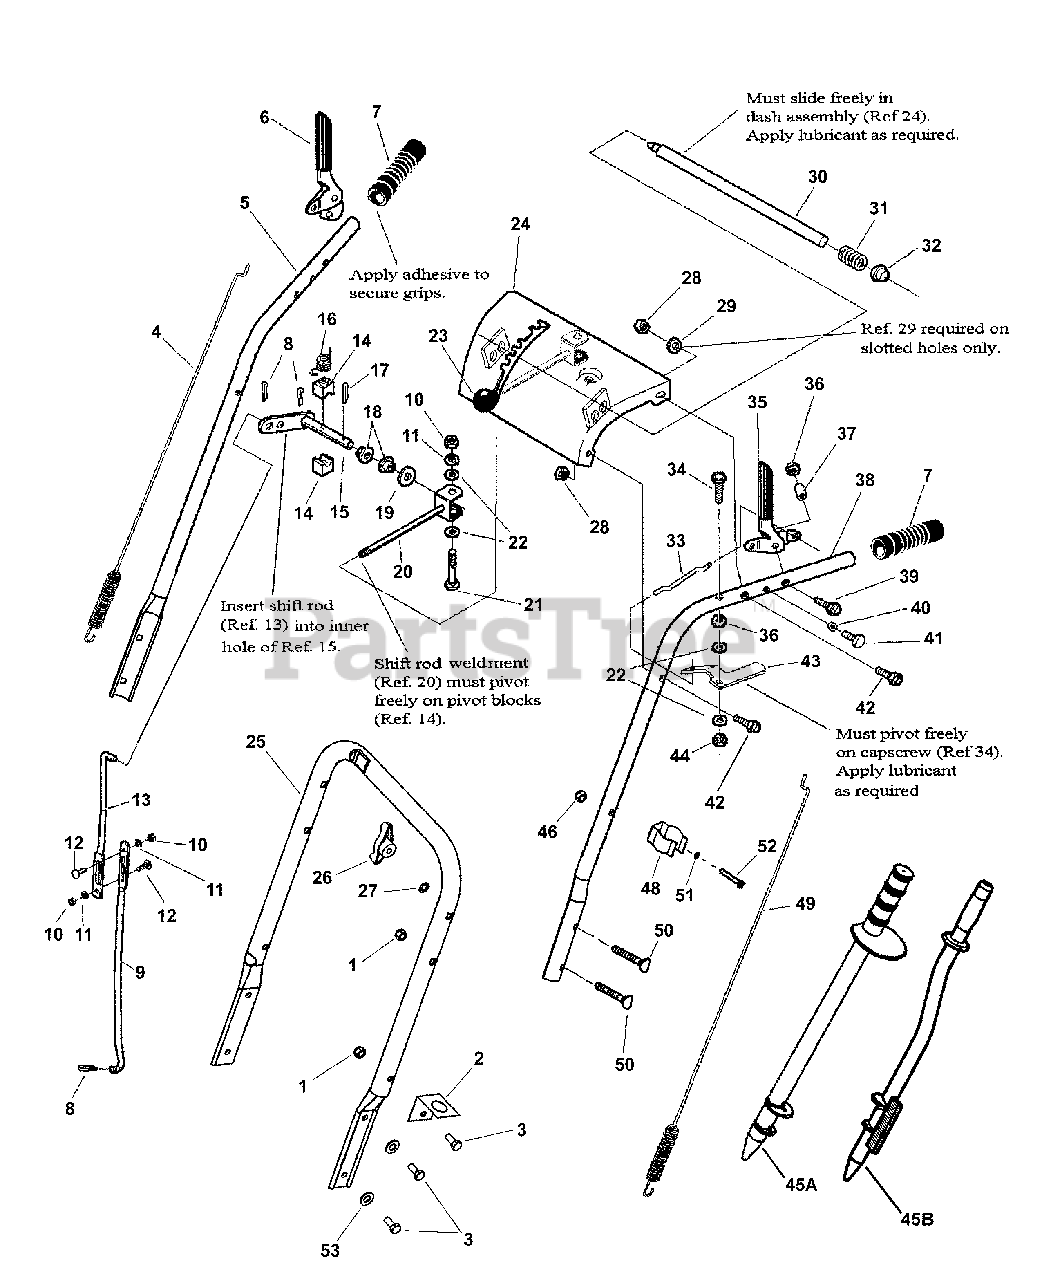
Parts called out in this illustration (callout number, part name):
1	NUT, 5/16-18 Hex Nyloc
2	BRACKET, Snow Stick- Lower
3	SCREW, 5/16-18 x 3/4" Hex Head Cap
4	CLUTCH CABLE, Auger Drive- RH
5	HANDLE, Upper, Right Hand
6	GRIP, Clutch, RH
7	GRIP, Foam, Black
8	HAIR PIN
9	ROD, Shift, Lower
10	NUT, 1/4-20 2B Hex
11	LOCKWASHER, 1/4" Spring
12	BOLT, 1/4-20 x 2" Short Square Neck Carriage, GR 5
13	ROD, Upper, Shift
14	BLOCK, Pivot
15	WELDMENT, Shift Rod Pivot
16	SPRING, Torsion
17	COTTER PIN, .125 x 1.00
18	BUSHING, .500 ID x .750 OD x .25
19	WASHER, 1/2" Flat (.531 ID x 1.250 OD x .08 Thick)
20	WELDMENT, Shift Rod
21	SCREW, 1/4-20 x 2-1/4" Hex Flange Lock
22	WASHER, .250 (.27 ID x .62 OD)
23	KNOB, Tapered - 3/8-16 Internal Thread- Red
24	WELDMENT, Dash
25	HANDLE, Lower
26	WING KNOB, 5/16-18
27	WASHER, 5/16" Internal Tooth Lock
28	NUT, 5/16-18 Hex Flange Nyloc
29	WASHER, .312 (.34 ID x .75 OD)
30	ASSEMBLY, Rod w/Pin
31	SPRING, Compression
32	PUSH NUT
33	ROD, Hold Down
34	SCREW, 1/4-20 x 2" Hex Head Cap, GR 5
35	GRIP, Clutch, LH
36	NUT, 1/4-20 Hex Centerlock
37	SPACER, Handle
38	HANDLE, Upper, Left Hand
39	SCREW, 1/4-20 x 1-1/2" Hex Head Cap
40	SPACER, .268 ID x .394 x .165
41	SCREW, 1/4-20 x 3/4" Pan Head Torx Self-Tap
42	SCREW, 5/16-18 x 1-1/2" Hex Head Cap, GR 5
43	LEVER, Pivot
44	NUT, 1/4-20 Hex Nyloc
45A	SNOW STICK
45B	SNOW STICK w/Brush
46	NUT, #10-24 Hex Center Lock
47	ROD, Hand Control
48	HOLDER, Snostik- Upper
49	CLUTCH CABLE, Ground Drive- LH
50	BOLT, 5/16-18 x 2" Curved Head Square Neck GR 2
51	WASHER, #10 Internal Tooth Lock
52	SCREW, #10-24 x 2" Hex Washer Head Machine, GR 5
53	LOCKWASHER, Spring .312
54	BUSHING, .250 ID x .375 OD x .750
55	PIN, Clevis
56	SPRING, Compression
